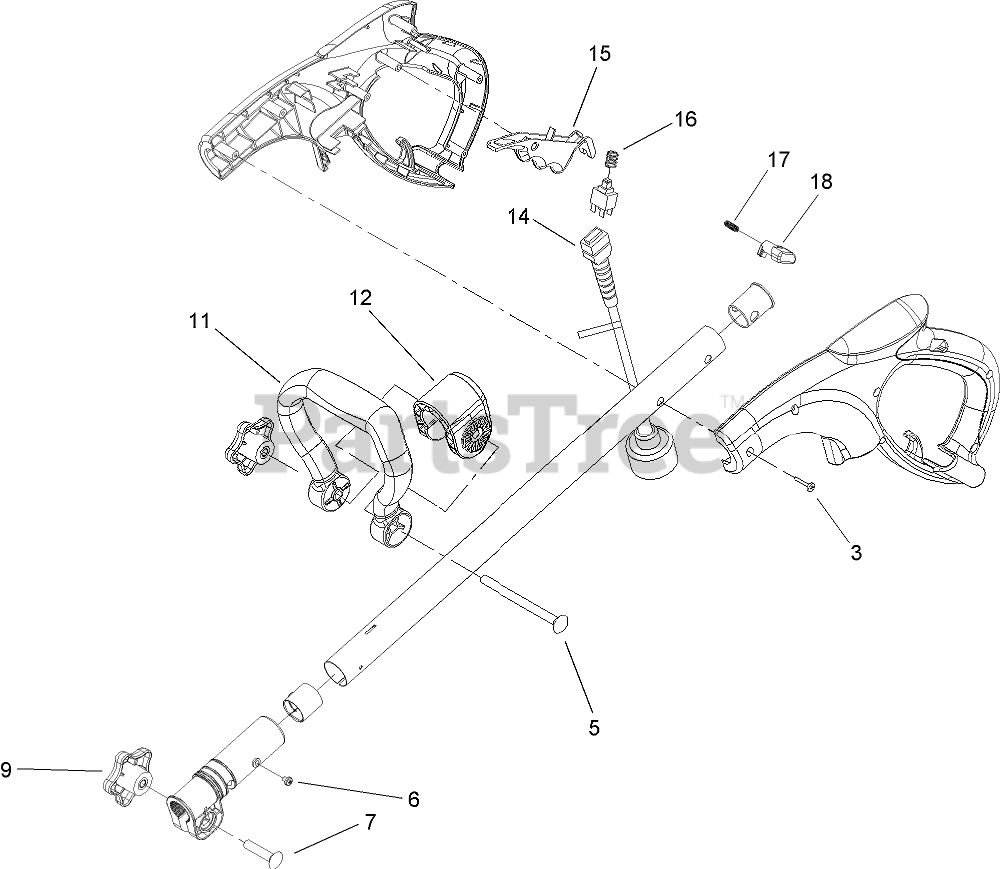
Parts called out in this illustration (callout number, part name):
3	SCREW-PPH
5	SCREW-CARR
6	SCREW-SELF TAPPING
7	BOLT-CARR
9	KNOB-HANDLE
11	HANDLE-ASSIST
12	COLLAR-HANDLE, ASSIST
14	WIRE ASM
15	TRIGGER-TRIM
16	SPRING
17	SPRING-COMPRESSION, SAFETY
18	BUTTON-SAFETY
